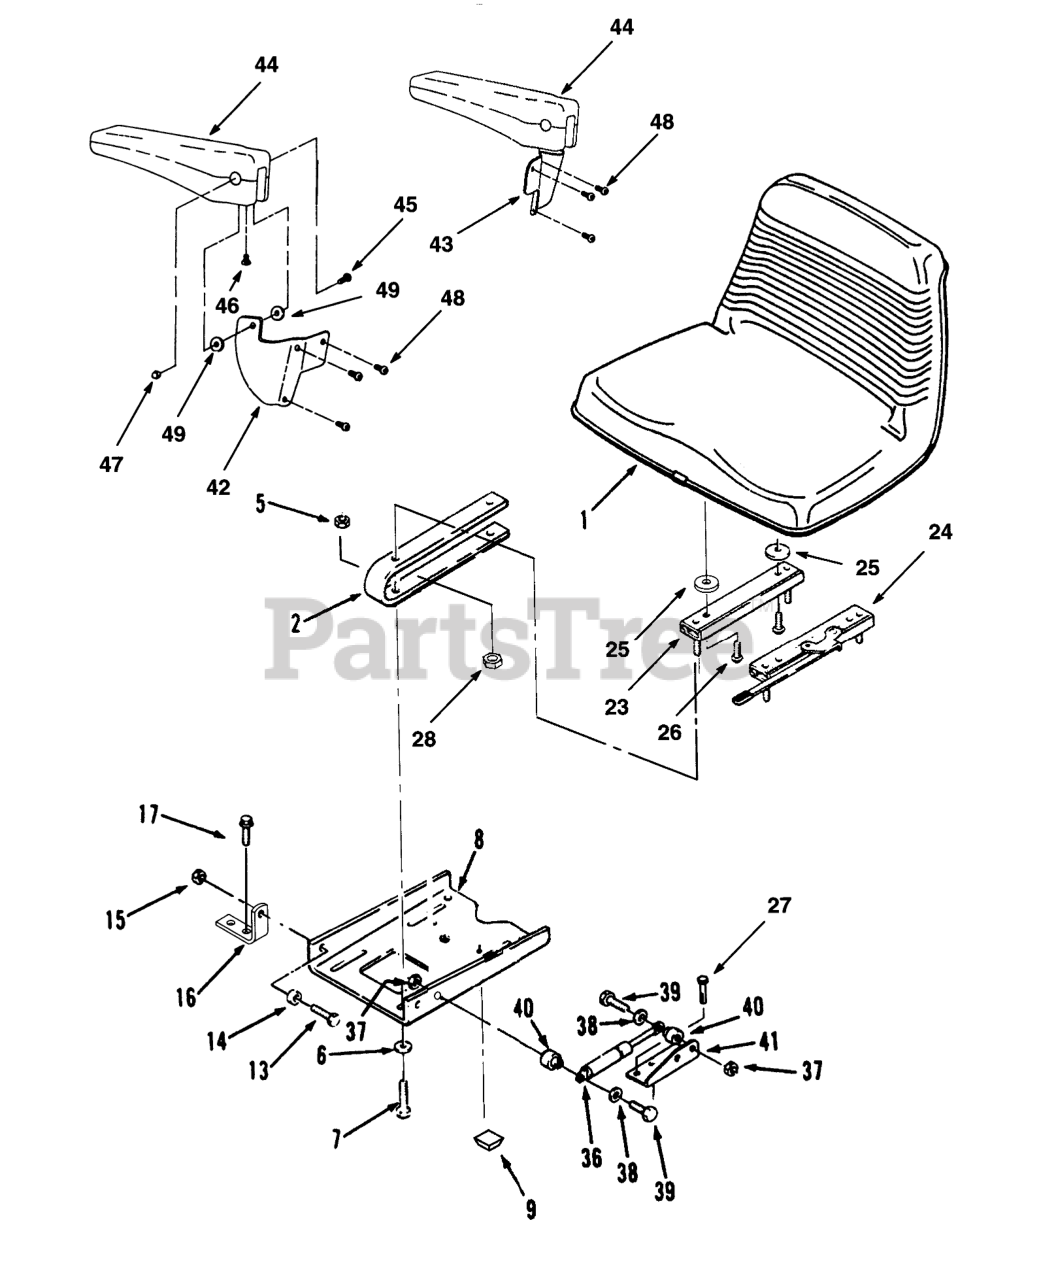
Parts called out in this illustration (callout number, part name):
1	Seat
2	Seat Spring
5	NUT-LOCK, NI
6	WASHER-PLAIN
7	SCREW-HH
8	Plate-SeatPivot
9	BUMPER SJ5514 BLACK
13	SCREW-HH
14	BUSHING
15	NUT-LOCK, NI
16	BRACKET-PIVOT
17	Bolt
23	ADJUSTER-R.H. SEAT
24	Adjuster-Seat
25	SPACER-NYLON
27	Bolt
28	Nut
36	GAS SPRING
37	NUT-LOCK, NI
38	WASHER-FLAT
39	SCREW-HH
40	SPACER
41	BRACKET-CYLINDER R
42	LH ARM BRACKET
43	RH ARM BRACKET
44	ARMREST
45	3/8-16X1-1/2 SCREW
46	3/8-16 X 3/4 SCREW
47	3/8-16 ACORN LOCKNUT
48	3/8-16 X 5/8 SCREW
49	NYLON SPACER
